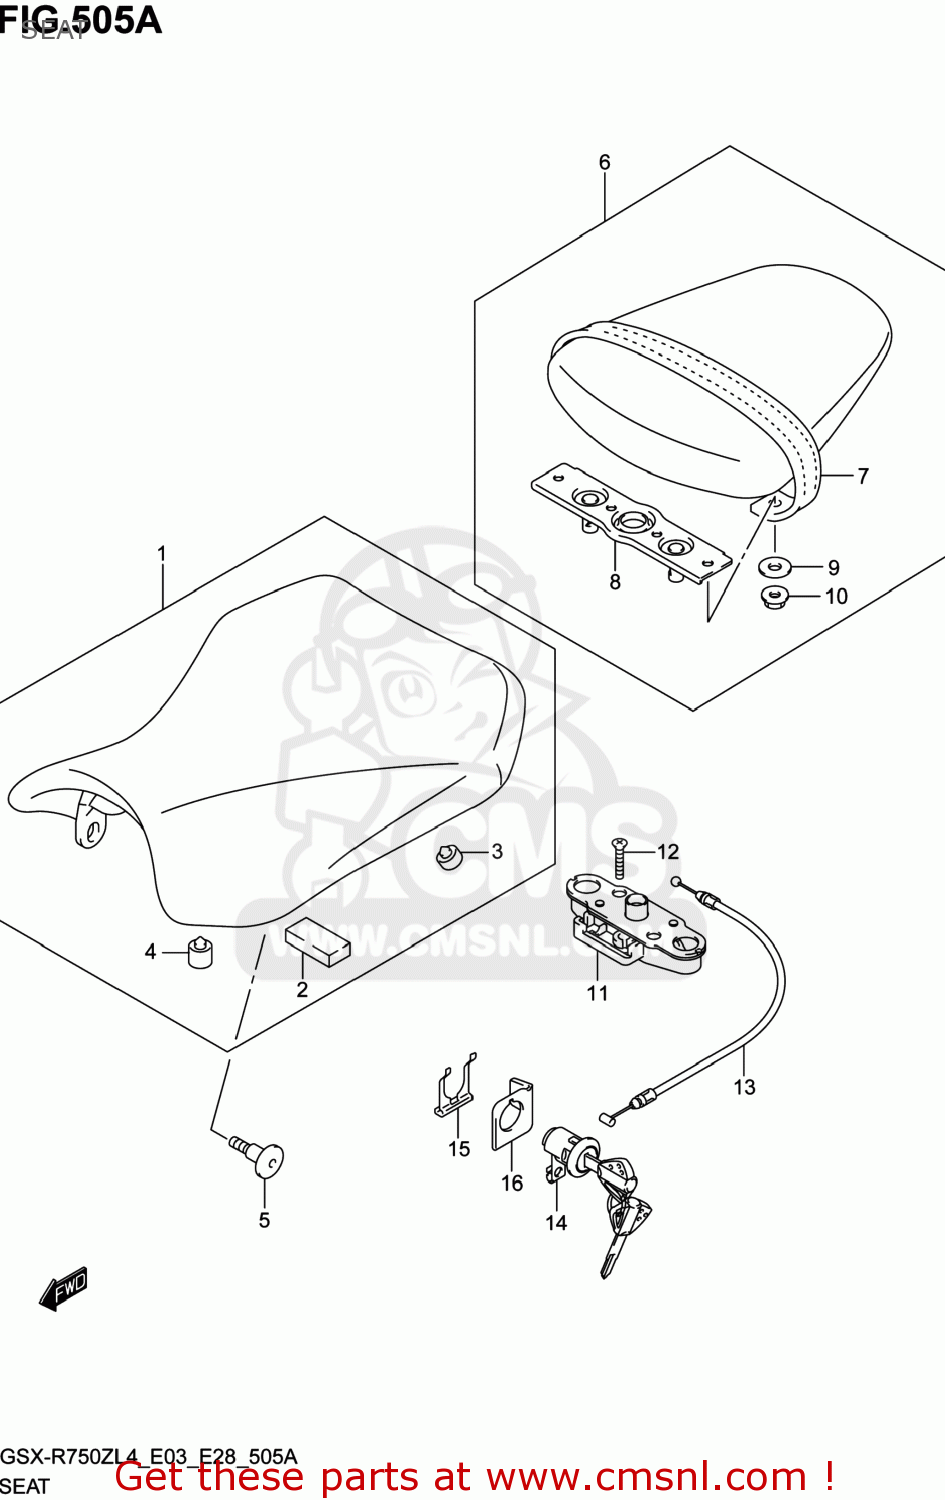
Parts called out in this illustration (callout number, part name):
1	SEAT ASSY
2	CUSHION
3	CUSHION
4	CUSHION
5	SCREW(6X20)
6	SEAT ASSY,PILLION
7	BAND ASSY,SEAT
8	STRIKER
9	WASHER(6.5X20X1.6)
10	NUT
11	BRACKET,SEAT SUPPORT
12	SCREW
13	CABLE,SEAT LOCK
14	LOCK SET,SEAT
15	PLATE,SEAT LOCK ASSY
16	GUIDE,SEAT LOCK CABLE
